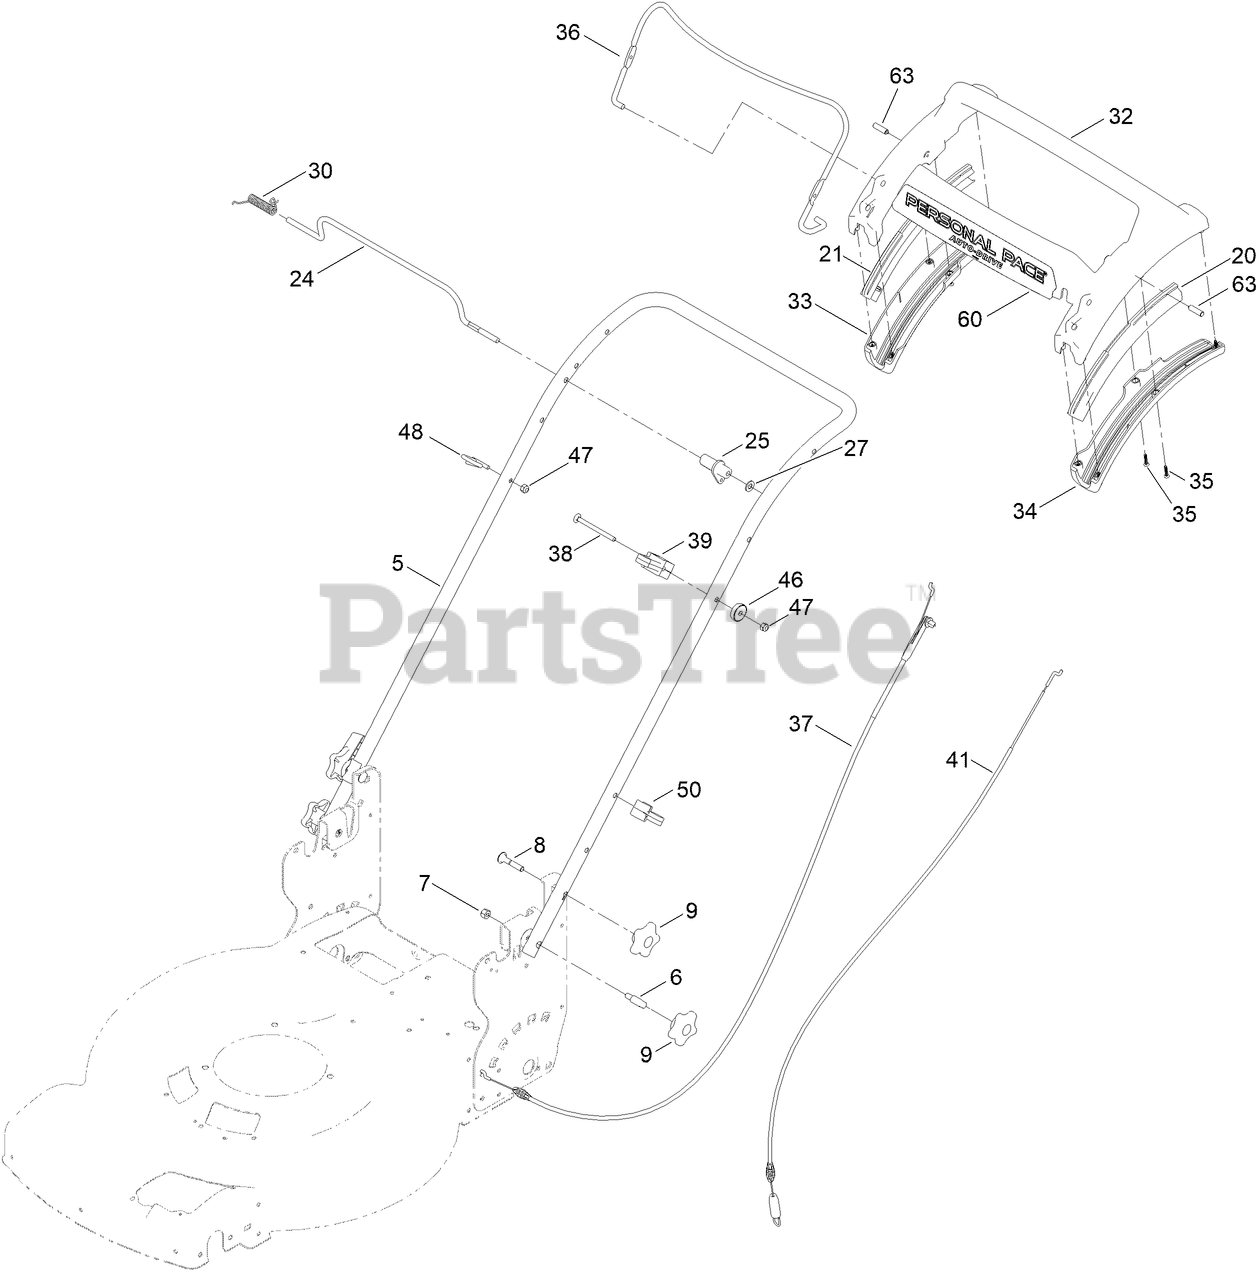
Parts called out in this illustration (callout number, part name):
5	HANDLE-CURVED
6	BOLT-SHOULDER, HANDLE
7	NUT-LOCK, NI
8	SCREW-CARR
9	KNOB-HANDLE
20	GUIDE-CURVED, LH (RWD)
21	GUIDE-CURVED, RH (RWD)
24	ROD-CONTROL, TRACTION
25	LEVER-TRACTION, RWD
27	WASHER-PLAIN
30	SPRING-TORSION
32	HANDLE-PERSONAL PACE, CURVED
33	BOTTOM-HANDLE, RH
34	BOTTOM-HANDLE, LH
35	SCREW-PPH
36	BAIL-BRAKE
37	CABLE-BRAKE, PP BS
38	SCREW-CARR
39	ANCHOR-CABLE, RWD
41	CABLE-TRACTION, RWD (PP)
46	WASHER-CURVED
47	NUT-LOCK, NI
48	GUIDE-ROPE
50	GUIDE-CABLE
63	PIN-HANDLE, PP
